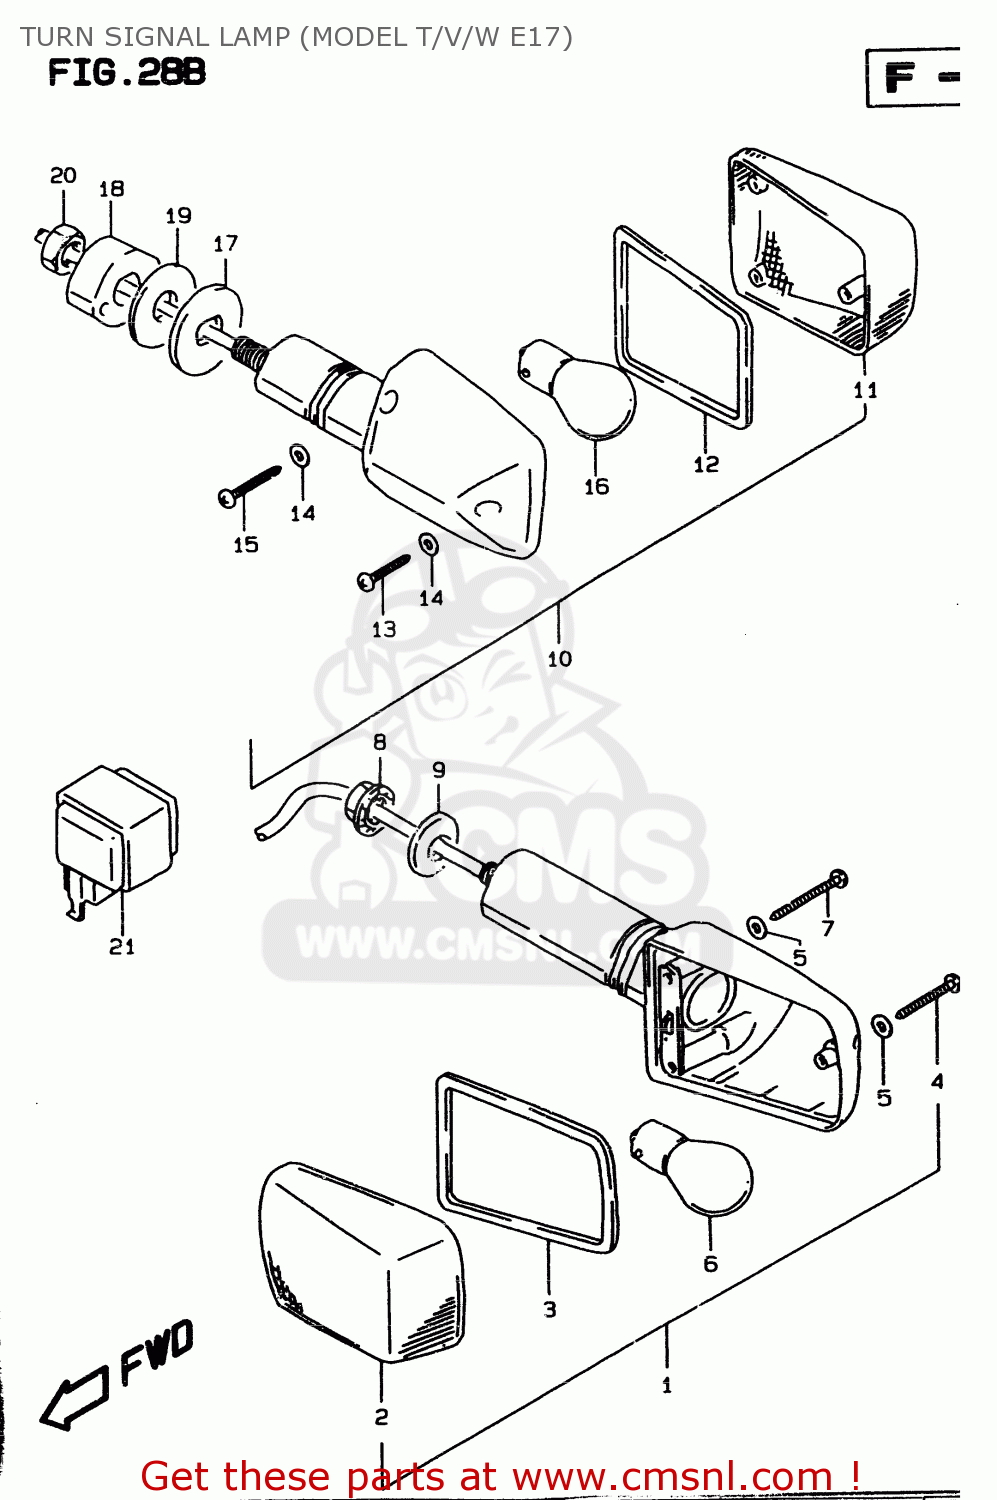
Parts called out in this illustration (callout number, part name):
1	LAMP ASSY,FR TURN SIGNAL
2	LENS
3	GASKET (NAS)
4	SCREW
5	GASKET (NAS)
6	BULB(12V21W)
7	SCREW(3X30)
8	NUT
9	GROMMET
10	LAMP ASSY,RR TURNSIGNAL
11	LENS
12	GASKET (NAS)
13	SCREW
14	GASKET (NAS)
15	SCREW(3X30)
16	BULB(12V21W)
17	SPACER,RR TURNSIGNAL
18	SPACER,FR TURNSIGNAL LAMP
19	WASHER(10.5X30X2.3)
20	NUT
21	RELAY ASSY
